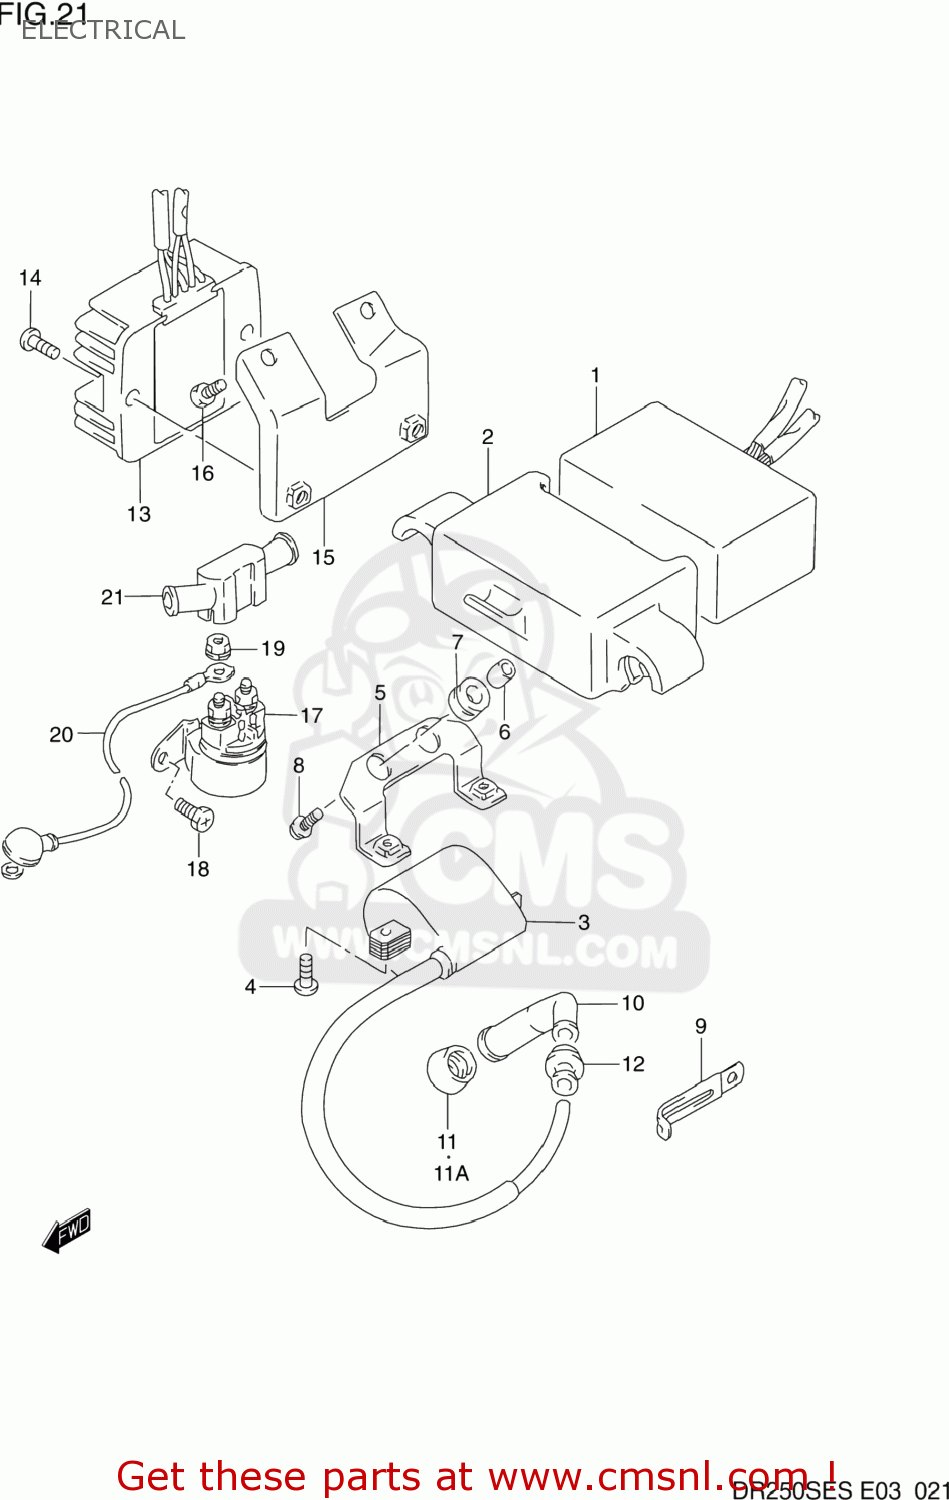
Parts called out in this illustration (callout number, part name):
1	CDI UNIT
2	CUSHION,CDI UNIT
3	COIL ASSY,IGNITION
4	SCREW
5	BRACKET,IGNITION COIL
6	SPACER (6.3X9.1X6.7)
7	CUSHION
8	BOLT
9	CLAMP(L:45)
10	CAP,SPARK PLUG
11	SEAL,SPARK PLUG CAP
11A	SEAL,SPARK PLUG
12	SEAL,HIGH TENSION CORD
13	RECTIFIER ASSEMBLY
14	SCREW
15	BRACKET,RECTIFIER
16	BOLT
17	RELAY ASSY,STARTING MOTOR
18	SCREW(6X10)
19	NUT
20	WIRE,STARTER MOTOR
21	CAP,STARTER RELAY TERMINAL
